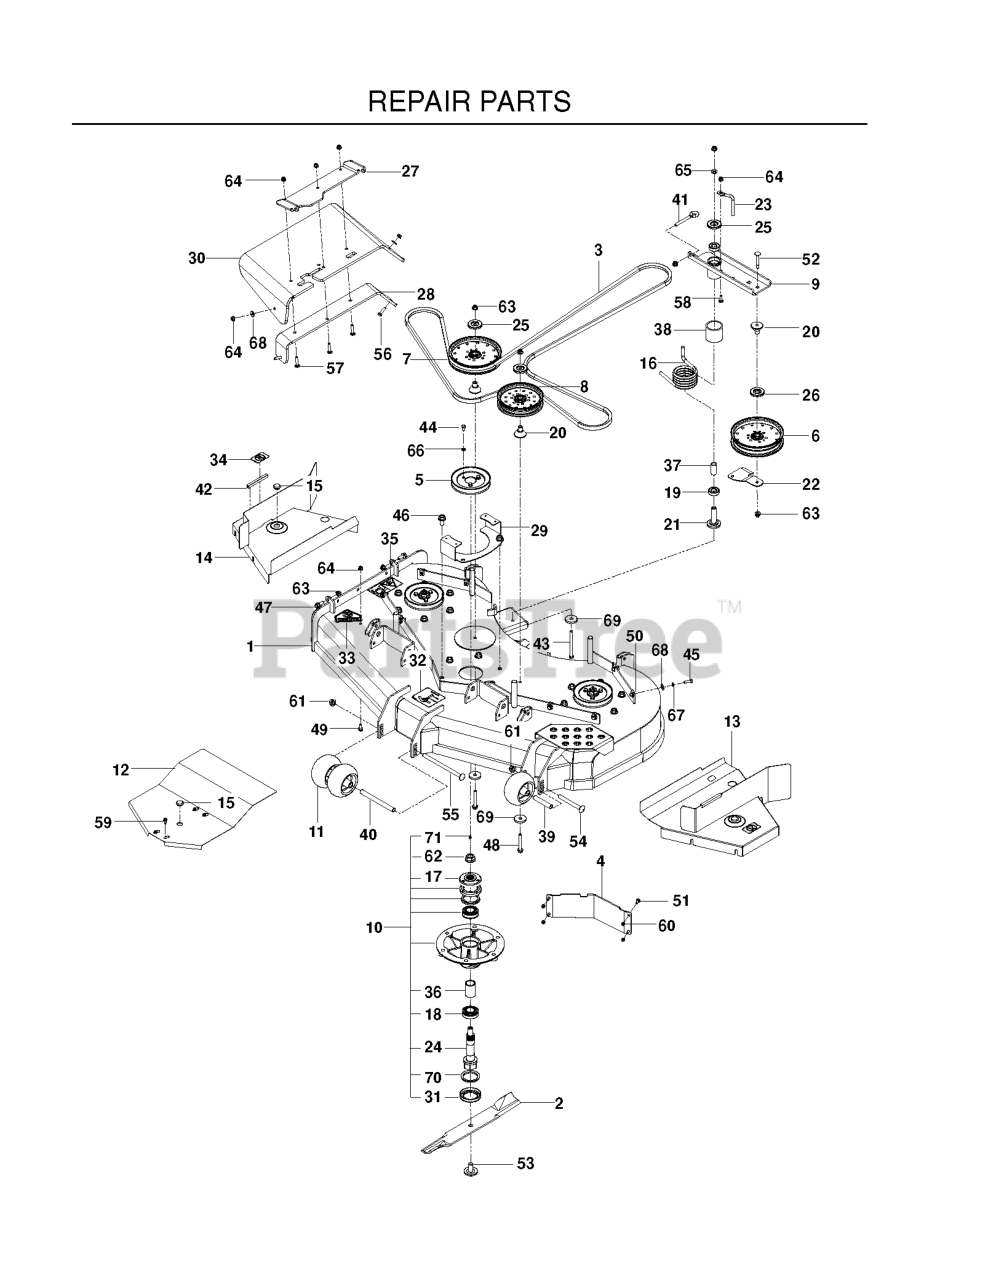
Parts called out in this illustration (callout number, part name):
1	WELDMT, 54" DECK ORANGE
2	BLADE, 19"
3	RP_BELT, "5V", 169.75"
4	BAFFLE, DIVERTER 54"/60" LH
5	PULLEY - 5.93 OVER PINS
6	PULLEY - IDLER 7"
7	PULLEY - 7" NARROW
8	PULLEY IDLER, 6" NARROW
9	IDLER.ARM.BLACK
10	SPINDLE ASM. 10"
11	ROLLER, GAUGE .635 BORN
12	GUARD CENTER.PZG54.BLK
13	WELDMENT.LH.PZG54.BLK
14	WELDMENT.RH.PZG54.BLK
15	PLUG, BUTTON HOLE
16	SPRING, TORSION, IDLER
17	HUB - PULLEY
18	BEARING - 206KRR8
19	BEARING, BALL
20	BEARING, IDLER ARM
21	BEARING, IDLER PIVOT
22	BELT.GUIDE.BLACK
23	BELT KEEPER
24	SHAFT - SPINDLE
25	DUST SHIELD
26	SHIELD, DUST
27	BRKT - CHUTE MTG BLACK
28	BRKT, CHUTE SUPPORT BLACK
29	BRACKET GUARD.PZG.BLK
30	CHUTE, DISCHARGE 48-52
31	CUP - DEBRIS
32	DECAL, BELT ROUTING
33	DECAL, CPSC
34	DECAL, NO STEP
35	DECAL, EURO SEVERING
36	SPACER - BEARING
37	SPACER, IDLER BEARINGS
38	SPACER, IDLER PIVOT
39	TUBE, ROLLER AXLE
40	TUBE, ROLLER AXLE LONG
41	EYE BOLT, 3/8 X 4"
42	RP.FLEX TRIM, BLK-LENGTH 1 FT
43	HCS 3/8-16 X 4-1/2 GR 8 ZD
44	HCS 5/16-18 X 1/2 GR 5 ZD
45	HCS 1/4C X 1
46	HHFS 1/2-13 X 1 GR5 ZD
47	HHFS 3/8-16 X 1 GRD 5 ZD
48	HHFS 5/16-18 X 3 3/4
49	HHFS 5/16-18 X 3/4
50	U-CLIP 5/16-18 NUT RETAINER
51	1/4-20X3/4 CARR BLT
52	CARRIAGE BOLT 3/8-16 X
53	BLADE BOLT/WASHER
54	RHSNB 1/2-13 X 4.75 GR5 ZD
55	RHSNB 1/2-13 X 8 GR5 ZD
56	BOLT, CARRIAGE 5/16X1-1/4
57	RHSNB 5/16-18 X 1-1/2 GR 5 ZD
58	RHSNB 5/16C X 1
59	SCREW- 1/4-20 X 5/8
60	NUT.1/4-20.HEX.NYLOC.ZD
61	NUT, 1/2-13 HEX FLG NYLOC ZD
62	NUT FLANGE 3/4-16
63	NUT 3/8-16 HEX FLG NYLOC ZD
64	5/16-18 NYLOC FLANGE NUT
65	WASHER, 3/8 THICK
66	WASH 5/16 DISC SPRING ZD
67	WASHER.LOCK.HVY.HLCL.SPR.5/16
68	WASHER 5/16 FLAT
69	SPINDLE WASHER
70	V-RING, 55MM
71	ZERK
